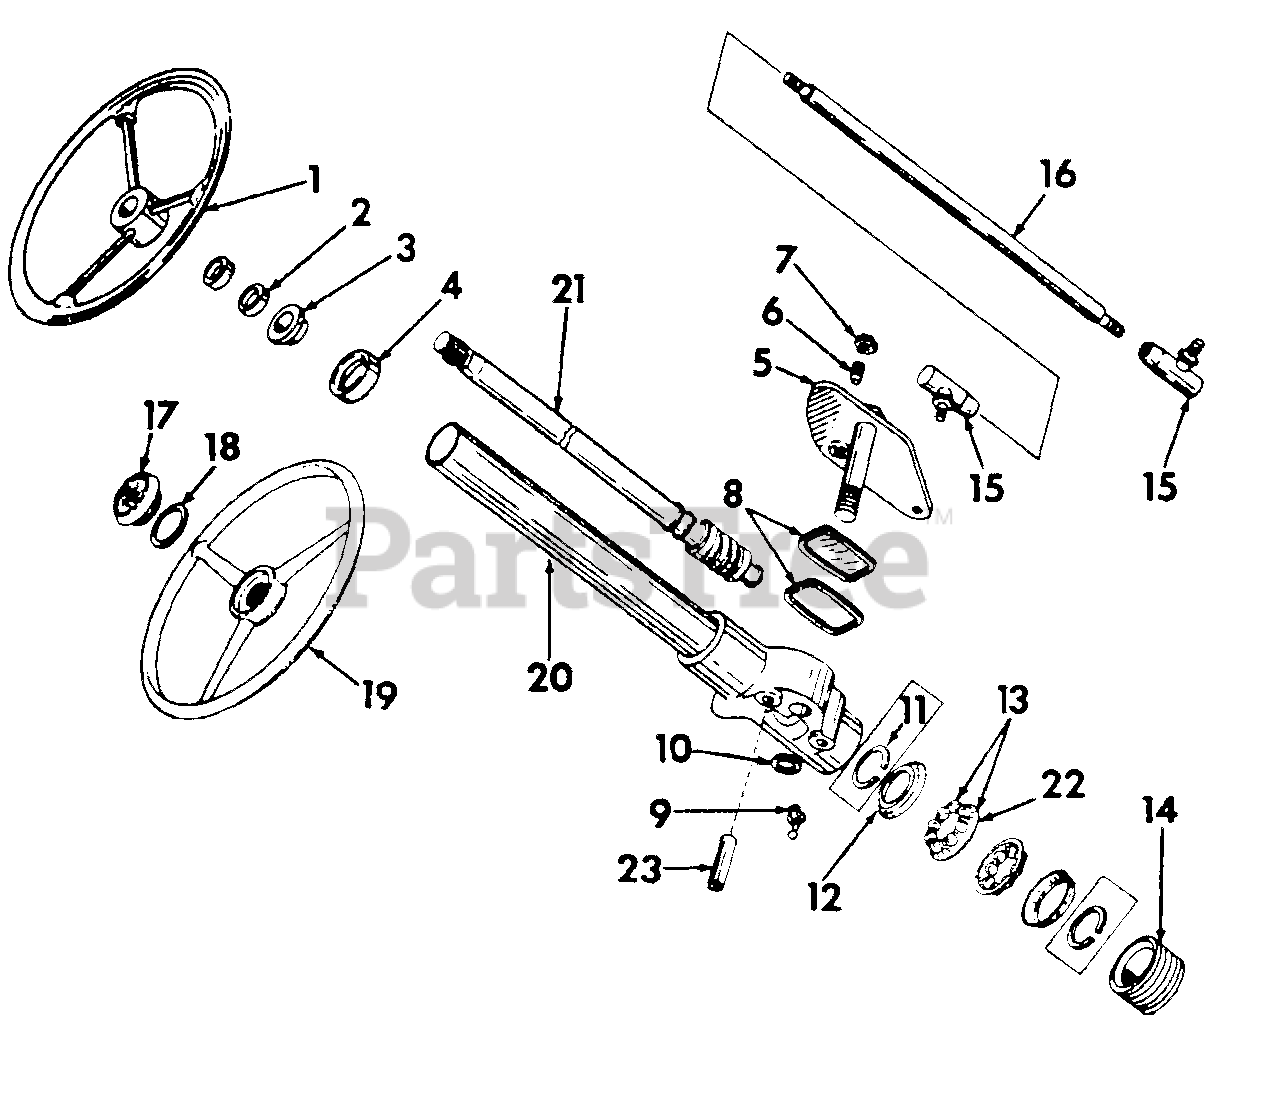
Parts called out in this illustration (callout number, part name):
1	Not used in this application
2	Seal, Steering Gear
3	Bearing, Upper Column
4	Retainer, Bearing
5	Lever & Bolt Assy
6	Stud, Cam Follower
7	Nut, Cam Follower Stud
8	Package, Seal & Seal Retainer
9	Fitting, 1/4 65 deg Angle Drive Lube
10	Washer, Flat, C-Z
11	Not used in this application
12	Retainer, Bearing Ball
13	Retainer & Ball Assy
14	Plug, Adjusting
15	Joint, Tie Rod End
16	Rod, Steering Gear Drag
17	Cap, Steering Wheel
18	Retainer, Steering Wheel Cap
19	Wheel, Steering
20	Tube Assy, Housing & Jacket
21	Cam & Tube Assy
22	Retainer, Ball
23	Spacer, Pipe
